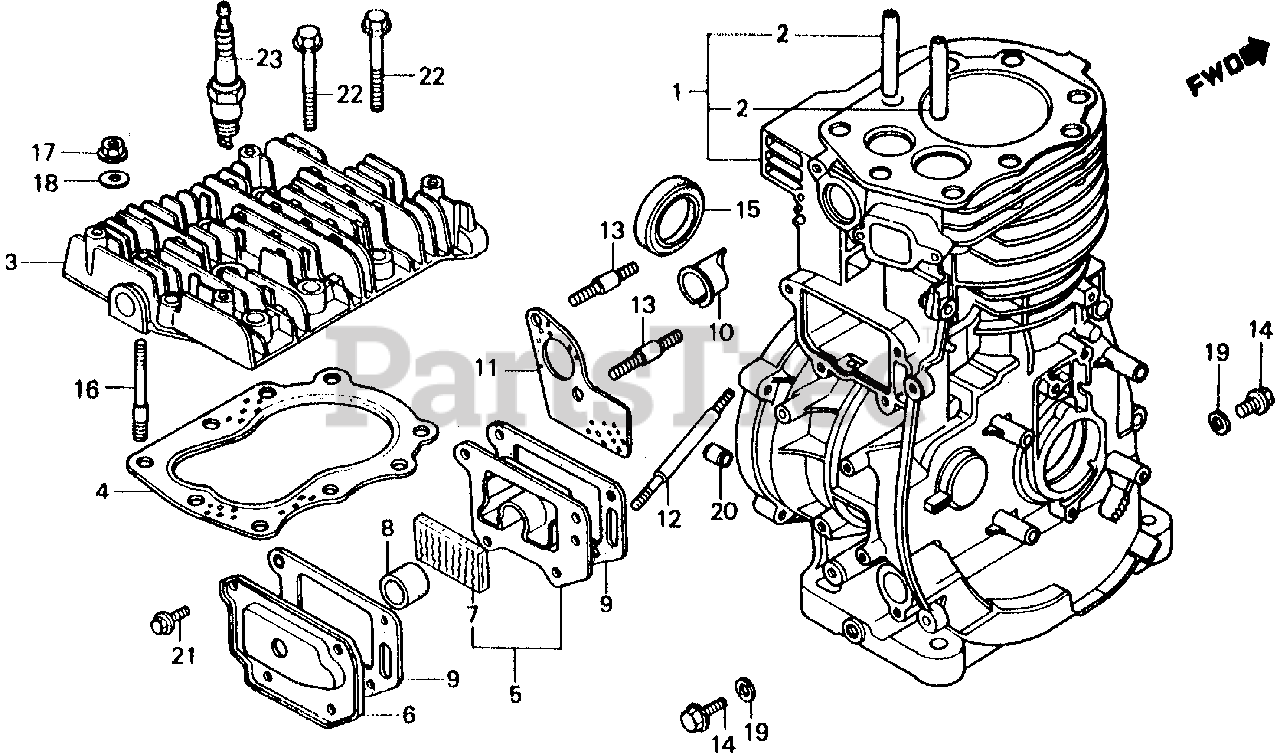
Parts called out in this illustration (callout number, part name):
2	GUIDE, VALVE
3	CYLINDER HEAD
4	GASKET, CYLINDER HEAD
5	CASE, BREATHER
6	COVER, TAPPET
7	FILTER, BREATHER
8	SEAL, BREATHER
9	GASKET, TAPPET COVER
10	LINER, EX. PIPE
11	GASKET, MUFFLER
12	BOLT, STUD (8X104)
13	BOLT, STUD (8X35)
14	BOLT, DRAIN PLUG
15	OIL SEAL (30X46X8)
16	BOLT, STUD (10X70)
16	BOLT, STUD (10X60)
16	BOLT, STUD (10X40)
17	NUT, FLANGE (10MM)
18	WASHER, PLAIN (10MM)
19	WASHER, DRAIN PLUG (12MM)
20	PIN A, DOWEL (8X14)
21	BOLT, FLANGE (6X12)
22	BOLT, FLANGE (10X55)
23	SPARK PLUG (BR-4HS) (NGK)
23	SPARK PLUG (W14F-U) (DENSO)
23	SPARK PLUG (W14FR-U) (DENSO)
